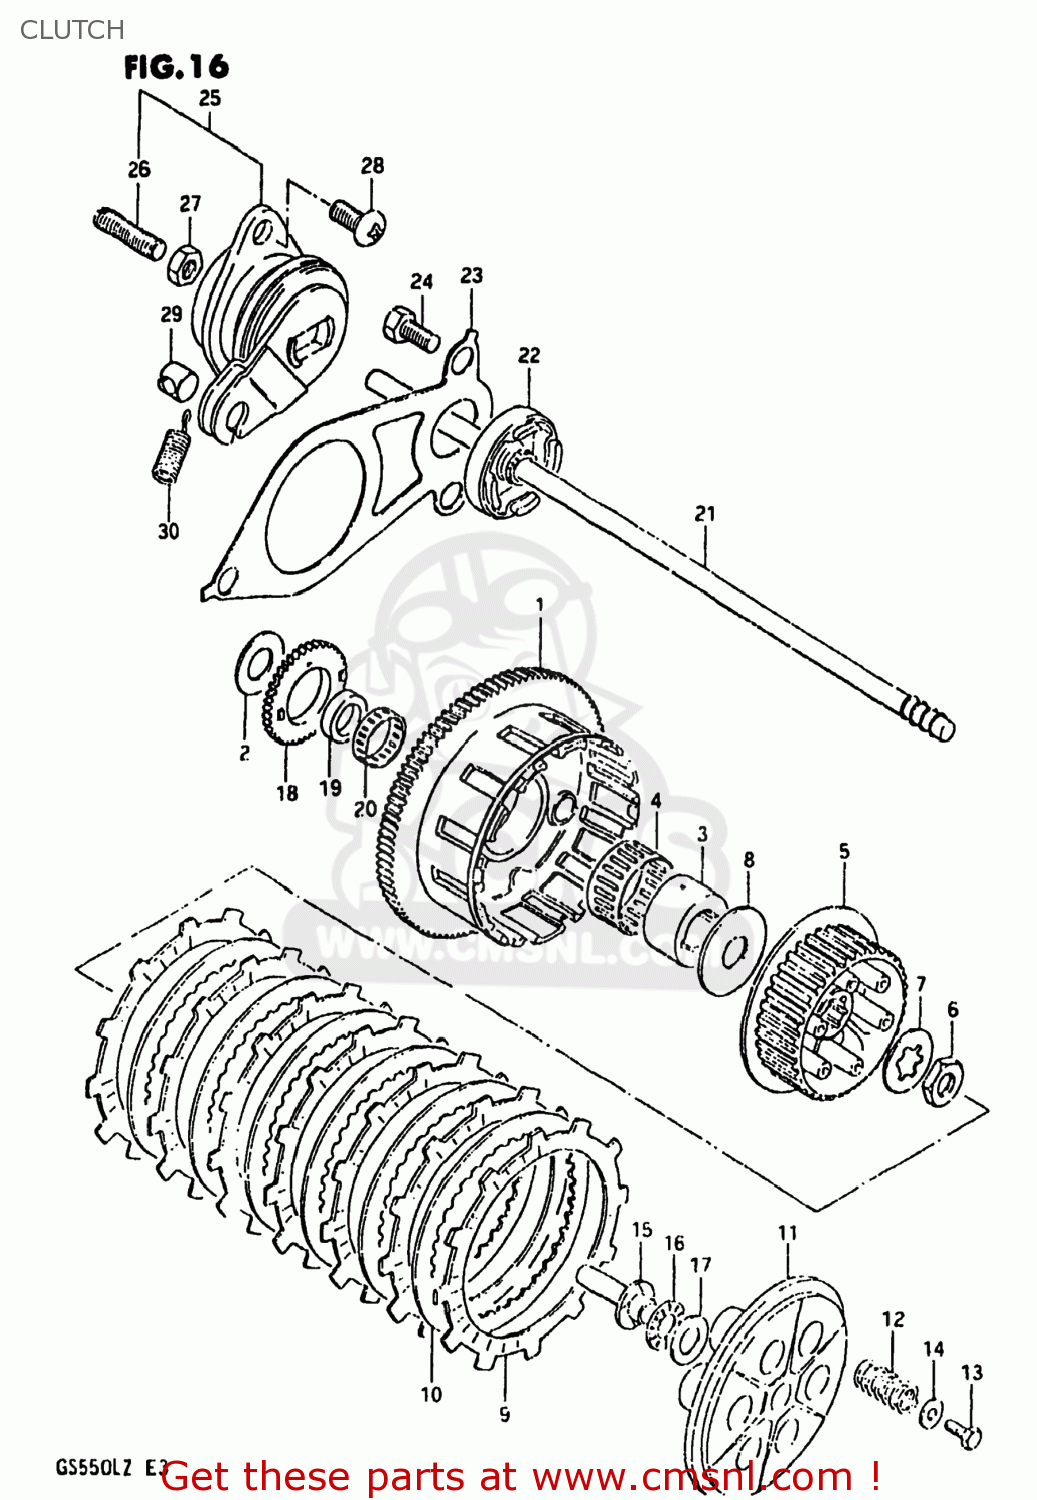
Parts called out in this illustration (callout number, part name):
1	GEAR ASSEMBLY,PRIMARY DRIVE NT:87
2	WASHER
3	SPACER,PRIMARY DRIVEN
4	BEARING
5	HUB,CLUTCH SLEEVE
6	NUT
7	WASHER,LOCK
8	WASHER(25X66X3.5)
9	PLATE,CLUTCH DRIVE (NAS)
10	PLATE,CLUTCH DRIVEN (NAS)
11	DISC,CLUTCH PRESSURE
12	SPRING
13	BOLT, UPPER
14	WASHER
15	PIECE,CLUTCH PUSH
16	BEARING(15X28X2)
17	WASHER
18	GEAR,ENG OIL PUMP DRIVE(NT:38)
19	SPACER,OIL PUMP DRIVE GEAR
20	BEARING(36X40X10)
21	ROD,CLUTCH PUSH
22	OIL SEAL
23	PLATE,CLUTCH PUSH ROD
24	BOLT
25	SCREW ASSEMBLY,CLUTCH RELEASE
26	SCREW
27	NUT 6MM
28	SCREW 6X12
29	PIECE,RELEASE ARM END
30	SPRING
